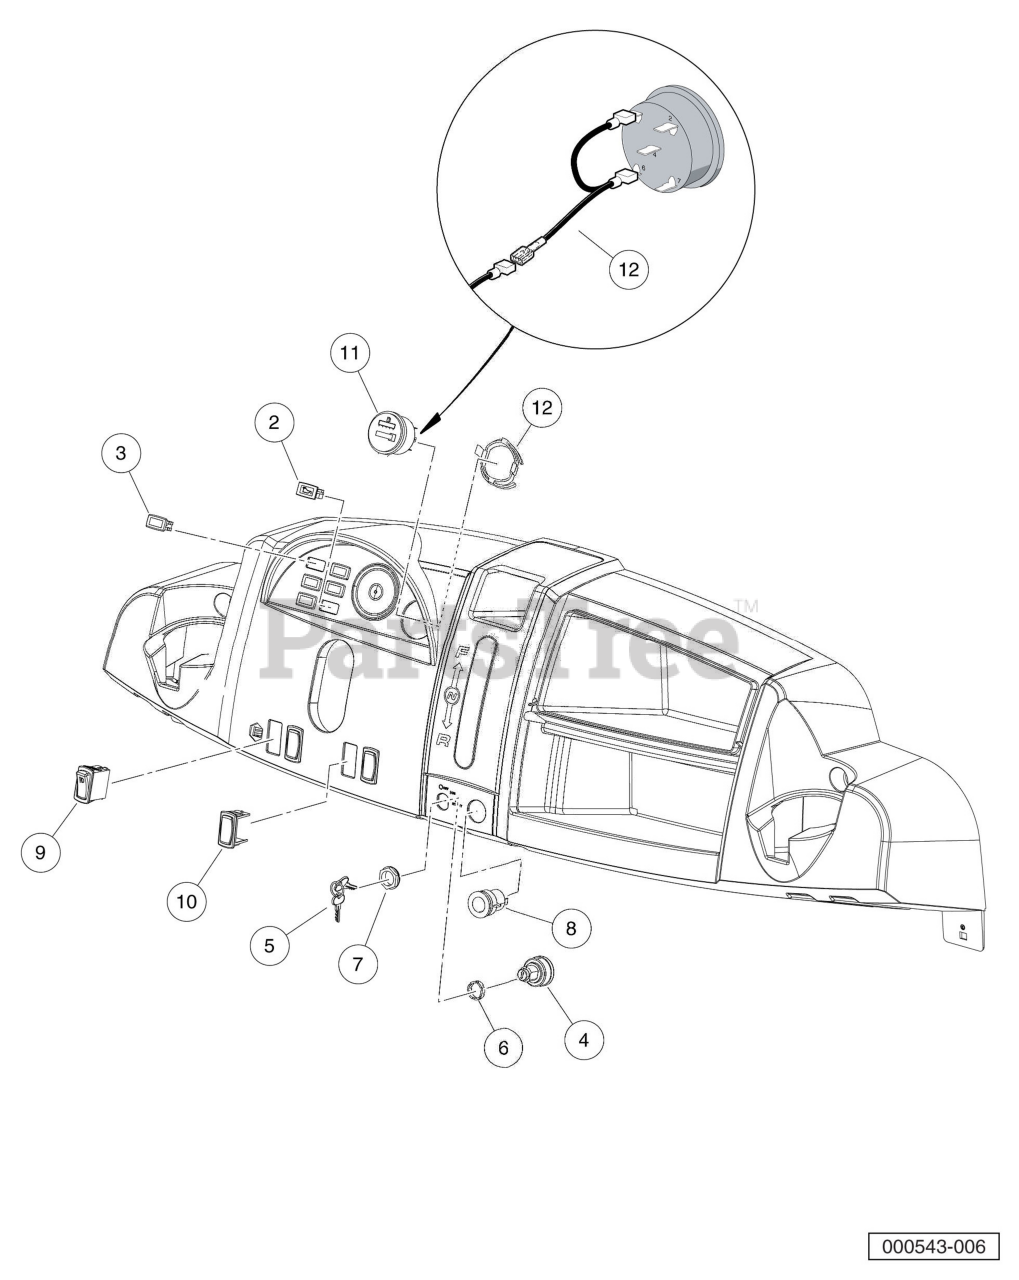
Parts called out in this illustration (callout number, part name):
2	Light, Oil
3	Plug, Hole
4	Key Switch 12v Key Start
6	Spacer, Keyswitch
7	Nut, Key Switch
8	Receptacle, Accessory
9	Switch, Rocker, Light
10	Cover, Hole, Switch, Rocker
11	Gauge Fuel-hour Sep Gnd
12	Clip, Meter, Round
13	Asm Wire Meter F-h Jumper
